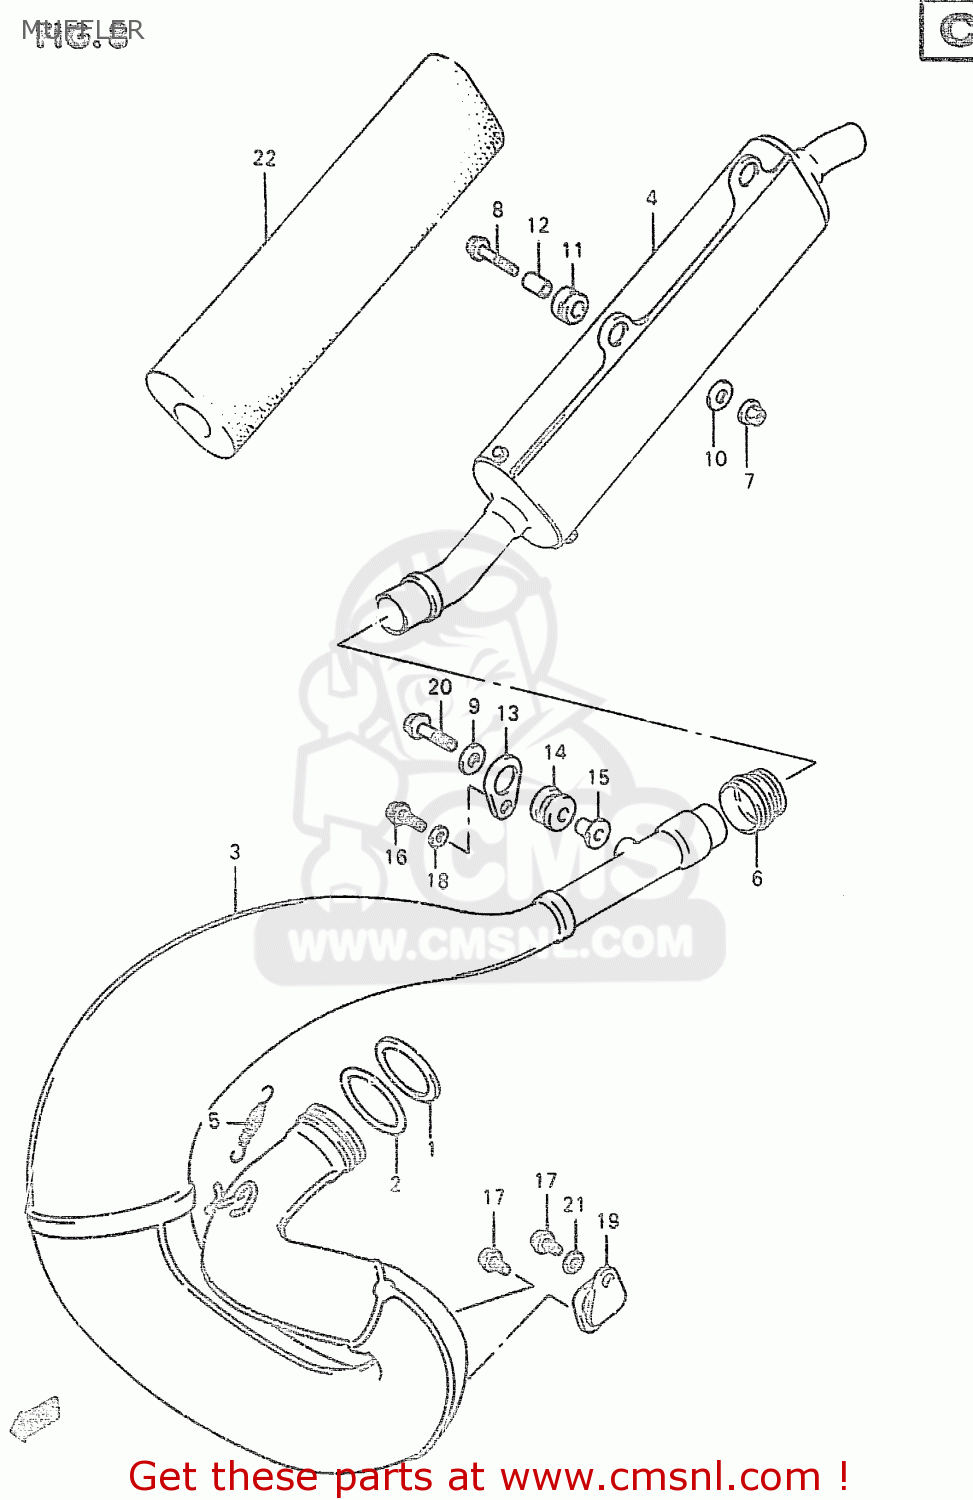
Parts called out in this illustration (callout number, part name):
1	WASHER,EXHAUST PIPE
2	O RING,EXHAUST PIPE
3	BODY,MUFFLER 1ST
4	BODY,MUFFLER 2ND
5	SPRING
6	CONNECTOR,MUFFLER
7	NUT
8	BOLT,G/S SWITC
9	WASHER(6.5X24X1.2)
10	WASHER(6.5X24X1.2)
11	CUSHION
12	SPACER(6.5X11.5X12)
13	PLATE,MUFFLER MTG
14	CUSHION,MUFFLER
15	SPACER,MUF MTG
16	SCREW
17	BOLT
18	WASHER
19	DAMPER,MUFFLER SUPPORT
20	BOLT
21	WASHER
22	SILENCER,MUFFLER
